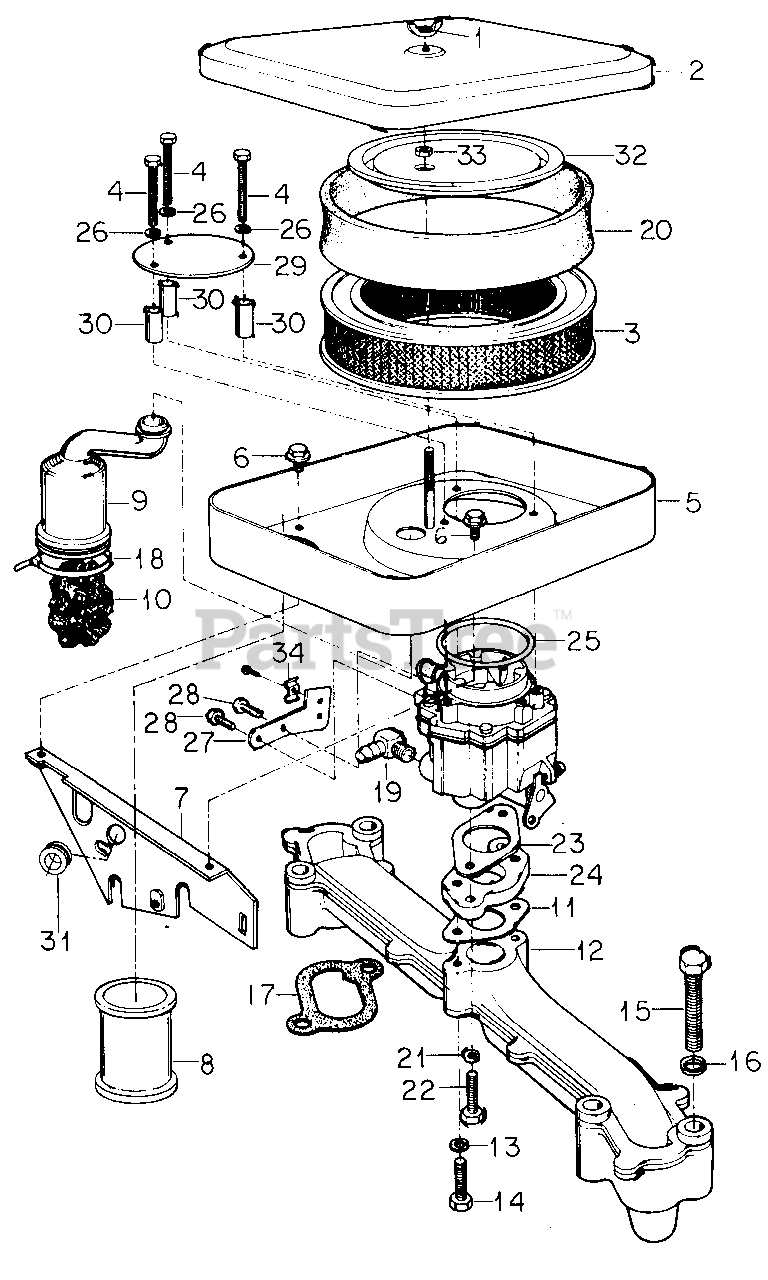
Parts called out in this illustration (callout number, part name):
1	Nut, 1/4 Wing
2	Cover, Air Cleaner
3	Filter, Air
4	Screw, Machine, #10-32 X 1-1/2
5	Housing, Air Cleaner
6	Screw, 1/4 X 1/2 Tap
7	Support, Air Cleaner
8	Tube, Air Intake
9	Tube, Crankcase Breather
10	Filter, Breather Tube
11	Gasket, Carburetor
12	Manifold, Intake OR
13	Washer, 1/4 Lock
15	Bolt, 5/16 X 2 Type 5
16	Washer, 5/16 Lock
17	Gasket, Manifold to Block
18	Tie, Breather Tube
19	Elbow, Adapter
20	Element, Air Filter Pre-Cleaner
21	Washer, 5/16 Lock
22	Bolt, 5/16 X 7/8 Type 5
23	Gasket, Carb to Adapter
24	Adapter, Carb Mounting
25	O-Ring, Carb Air Inlet
26	Washer, No. 10 Lock
27	Bracket, Choke Cable
28	Screw, 10-32 X 1/4 Cap
29	Plate, Carb Air Deflector
30	Spacer, Deflector Plate
31	Grommet, Rubber
32	Cover, Element
33	Nut, 1/4 Type 5
34	Clip, Choke Cable
